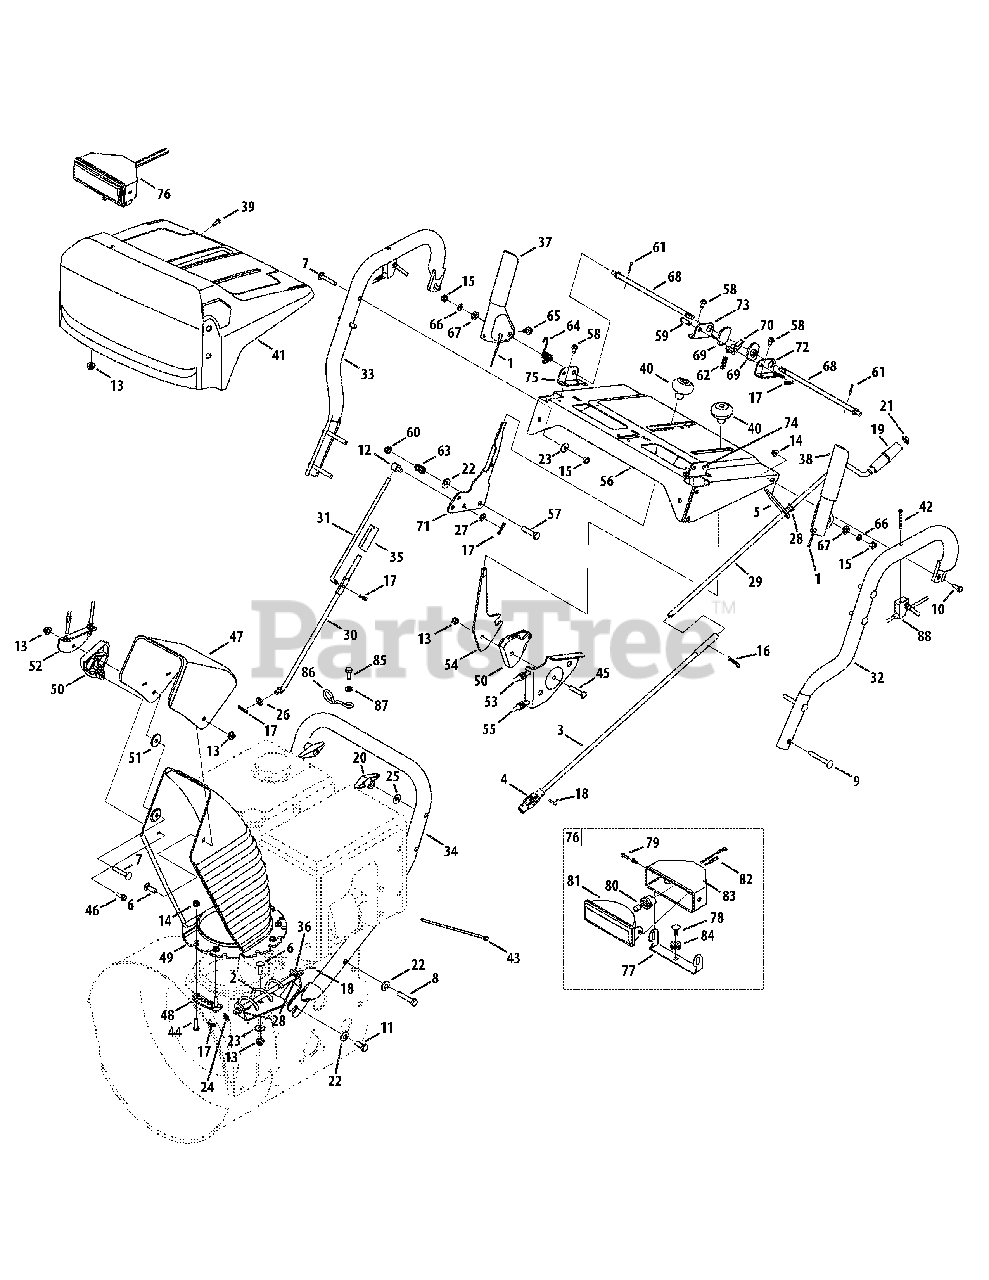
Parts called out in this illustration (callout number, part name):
1	Cable Ass’y, Auger/Drive
2	Chute Crank Assembly
3	Chute Crank Rod Assembly
4	Joint Block Assembly
5	Chute Crank Bracket
6	Carriage Screw, 5/16-18 x 1.0
7	Carriage Screw, 5/16-18 x 1.75
8	Hex Screw, 3/8-16 x 2.00
9	Carriage Screw, 5/16-18 x 2.5
10	Hex Screw, 1/4-20 x .75
11	Screw, Hex, 3/8-16 x 1.00
12	Ferrule, 5/16-18 x .312 Dia
13	Flange Lock Nut 5/16-18
14	Flange Lock Nut 1/4-20
15	Hex Lock Nut, 5/16-18 GR5
16	Internal Cotter Pin
17	Internal Cotter Pin
18	Spring Pin, .156 dia. x .875 Lg.
19	Knob, Crank
20	Wing Knob, 5/16-18
21	Push Cap, 3/8
22	Bell Wash, .375 x .87 x .063
23	Flat Washer, .349 x .879 x .063
24	Flat Wash, .375 x .738 x .063
25	Wash, Bell, .34 x .872 x .06
26	Flat Wash, .344 x .688 x .065
27	Flat Washer, .344 x .750 x .120
28	Plastic Bushing, .38 ID
29	Upper Chute Crank Rod
30	Lower Shift Rod
31	Upper Shift Rod
32	Handle, Upper LH
33	Handle, Upper RH
34	Handle, Lower
35	Shift Rod Connector
36	Chute Crank Bracket
37	Engagement Handle, RH
38	Engagement Handle, LH
39	Screw, #10-16 x .625
40	Shift Knob
41	Handle Panel
42	Screw, #10-24 x 1.75
43	Cable Tie
44	Hex Screw 1/4-20 x 1.0
45	Hex Screw 5/16-18 x 1.5
46	Hex Screw, 1/4-15 x .75
47	Upper Chute, 6.0
48	Chute Flange Keeper
49	Lower Chute
50	Cbl. Guide, Chute Tilt
51	Flat Wash, .344 x 1.125 x .12
52	Cable Bracket
53	Chute Control Cable, 66"
54	Chute Tilt Handle
55	Chute Control Cable w/Clip
56	Handle Panel
57	Hex Screw, 3/8-24 x 1.5
58	Hex Screw, 1/4-20 x .5
59	Clevis Pin, .312 x 1.0
60	Insert Nut, 3/8-24
61	Cotter Pin, 3/32 x .75
62	Compression Spring
63	Compression Spring
64	Torsion Spring
65	Rubber Bumper
66	Lock Washer, 5/16
67	Flat Wash, .35 Sq x .72 x .134
68	Cam Rod
69	Handle Lock Cam
70	Handle Lock Pawl
71	Shift Handle
72	Handle Support Bracket - LH
73	Handle Support Bracket - RH
74	Handle Support Bracket - RH
76	Light Assembly
77	Lamp Mount Bracket
78	Carriage Bolt, 5/16-18 x .750
79	Screw, M4 x .7
81	Lamp Housing
82	Harness
83	Housing
84	Grommet
85	Hex Head Screw, MB-1.25 x 20
86	Cable Guide
87	Flat Washer, .330 x .630 x .0635
88	Trigger Control
